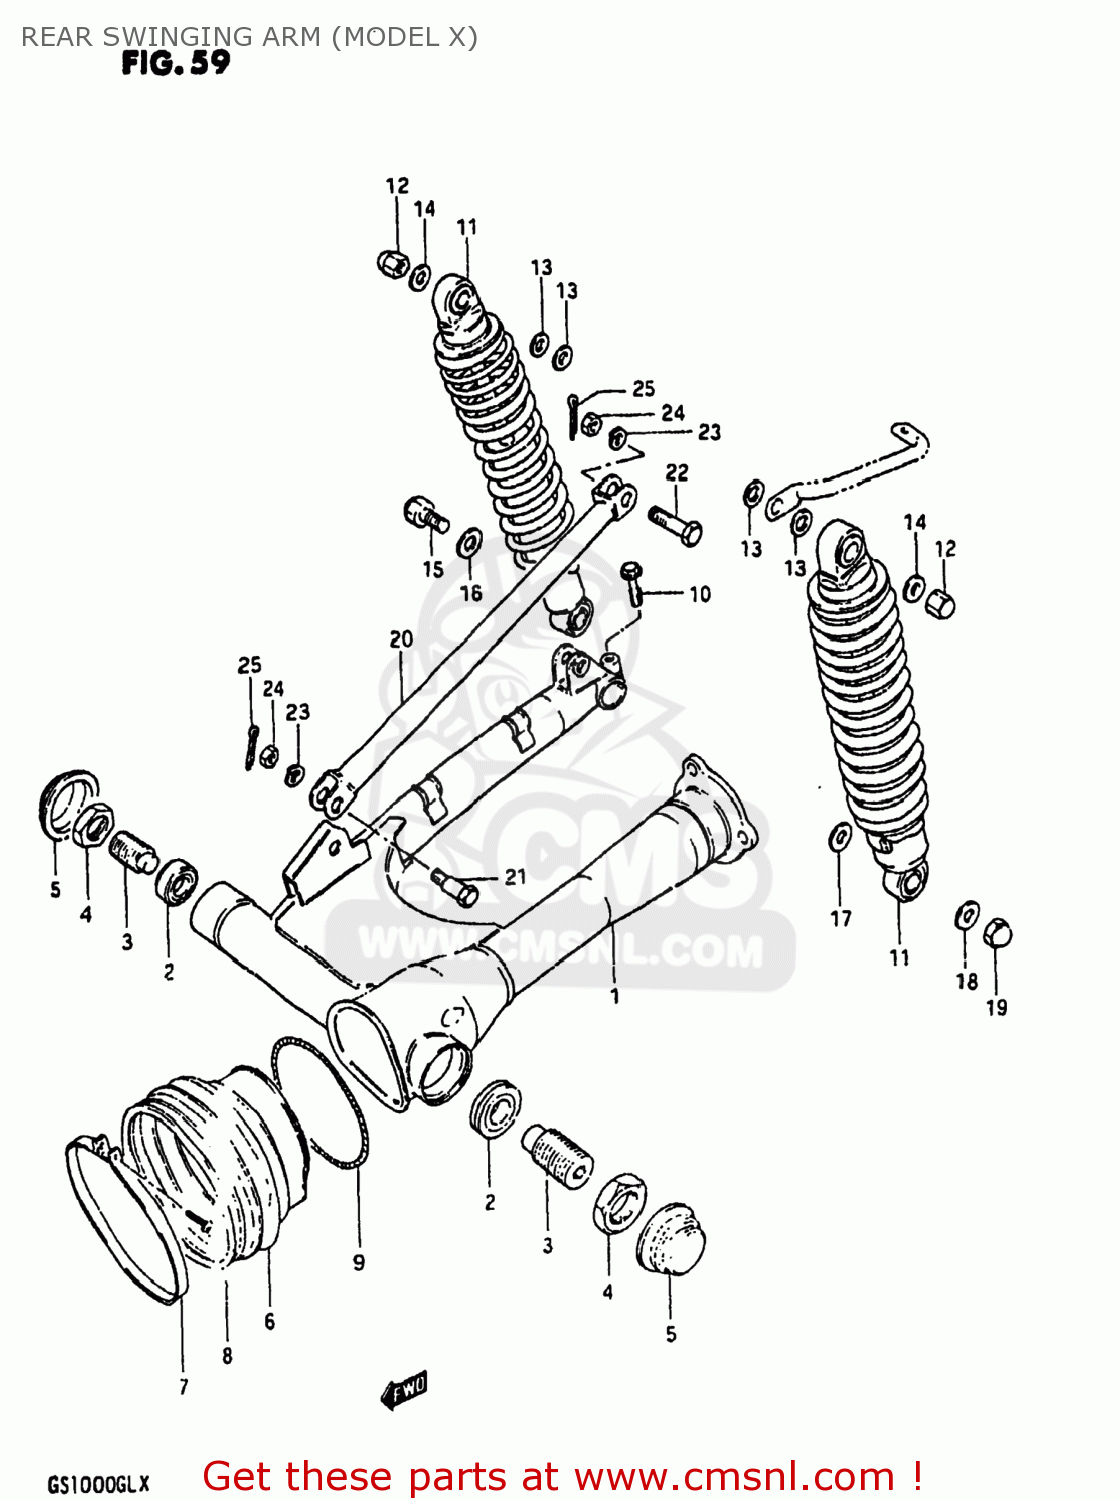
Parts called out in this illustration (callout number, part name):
1	SWING ARM SET,REAR (B
2	BEARING(17X40X13.25)
3	BOLT,REAR SWING ARM PIVOT
4	NUT
5	CAP,REAR SWING ARM PIVOT
6	BOOT,PROPELLER SHAFT
7	CLAMP
8	SCREW 4X25
9	SPRING,PROPELLER SHAFT
10	BOLT
11	ABSORBER ASSEMBLY,REAR SHOCK
12	NUT
13	WASHER
14	WASHER
15	BOLT 12X33
16	WASHER (12.5X24X1.6)
17	WASHER
18	WASHER
19	NUT, LOWER LH
20	TORQUE LINK,REAR
21	BOLT
22	BOLT(10X39)
23	WASHER
24	NUT
25	PIN 20X20
